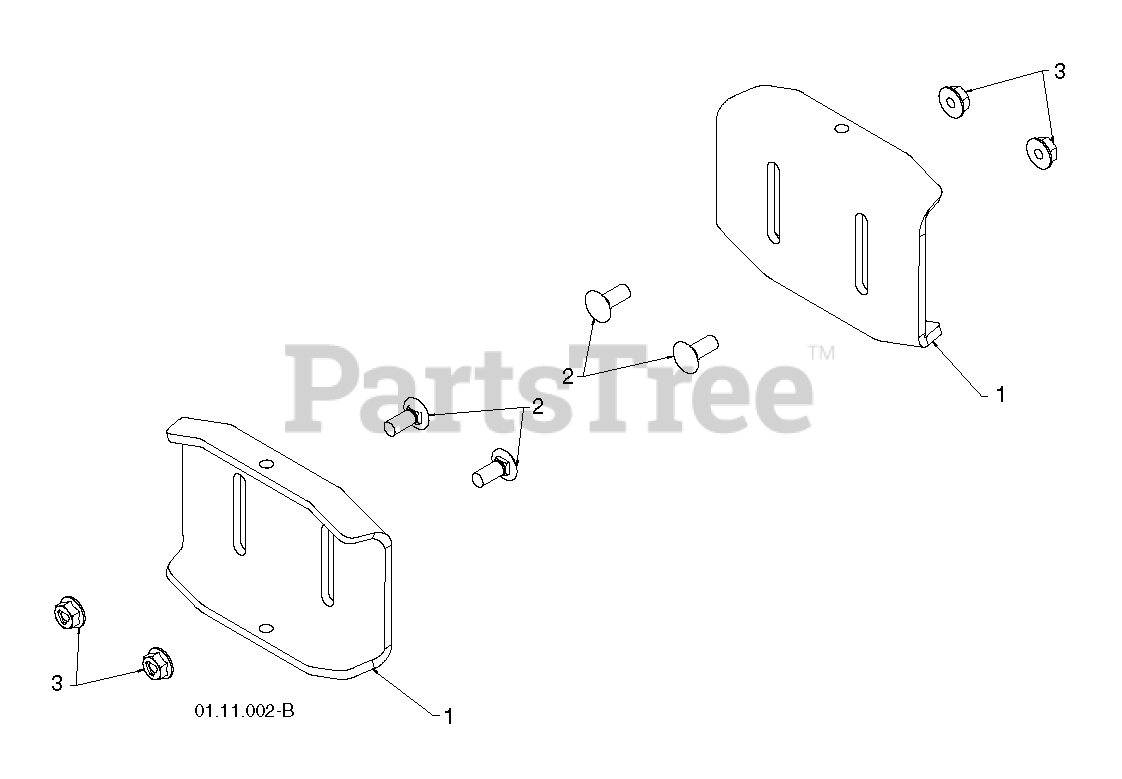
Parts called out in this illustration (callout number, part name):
1	SKID PLATE
2	BOLT
3	NUTNYLOK.FLRANGE.5/16-18
